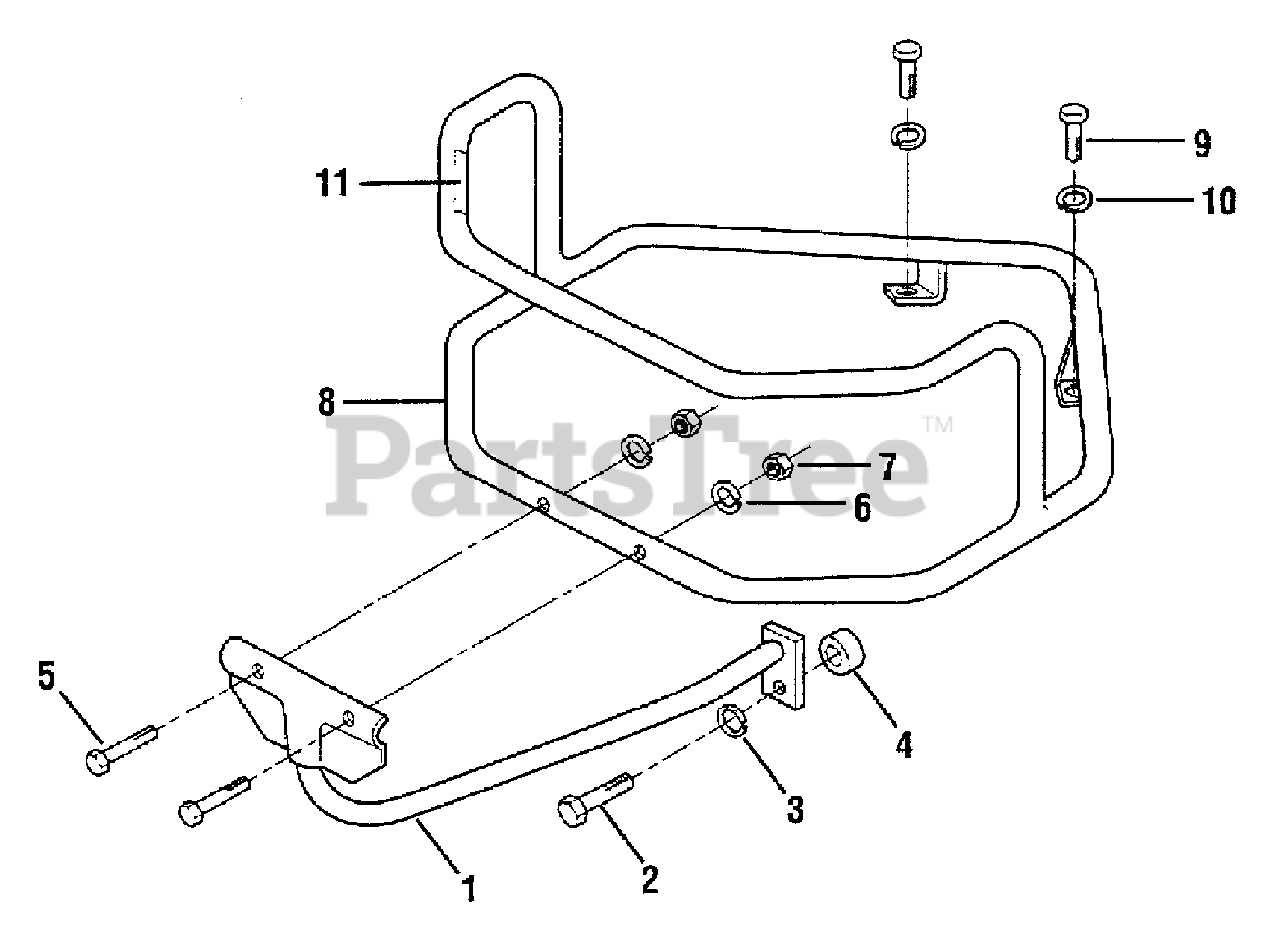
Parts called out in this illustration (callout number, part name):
1	Brace - bumper bottom
2	Bolt - hex hd., 1/2-13 x 1-1/2"
3	Lockwasher - spring lock, 1/2"
4	Spacer, 1/2"
5	Bolt - hex hd., 5/16-18 x 1-1/2"
6	Lockwasher - spring lock, 5/16
7	Nut - hex, 5/16"-18
8	Bumper wraparound
9	Bolt - hex hd., 3/8-16 x 1"
10	Lockwasher - spring lock, 3/8" 2
11	Decal -
